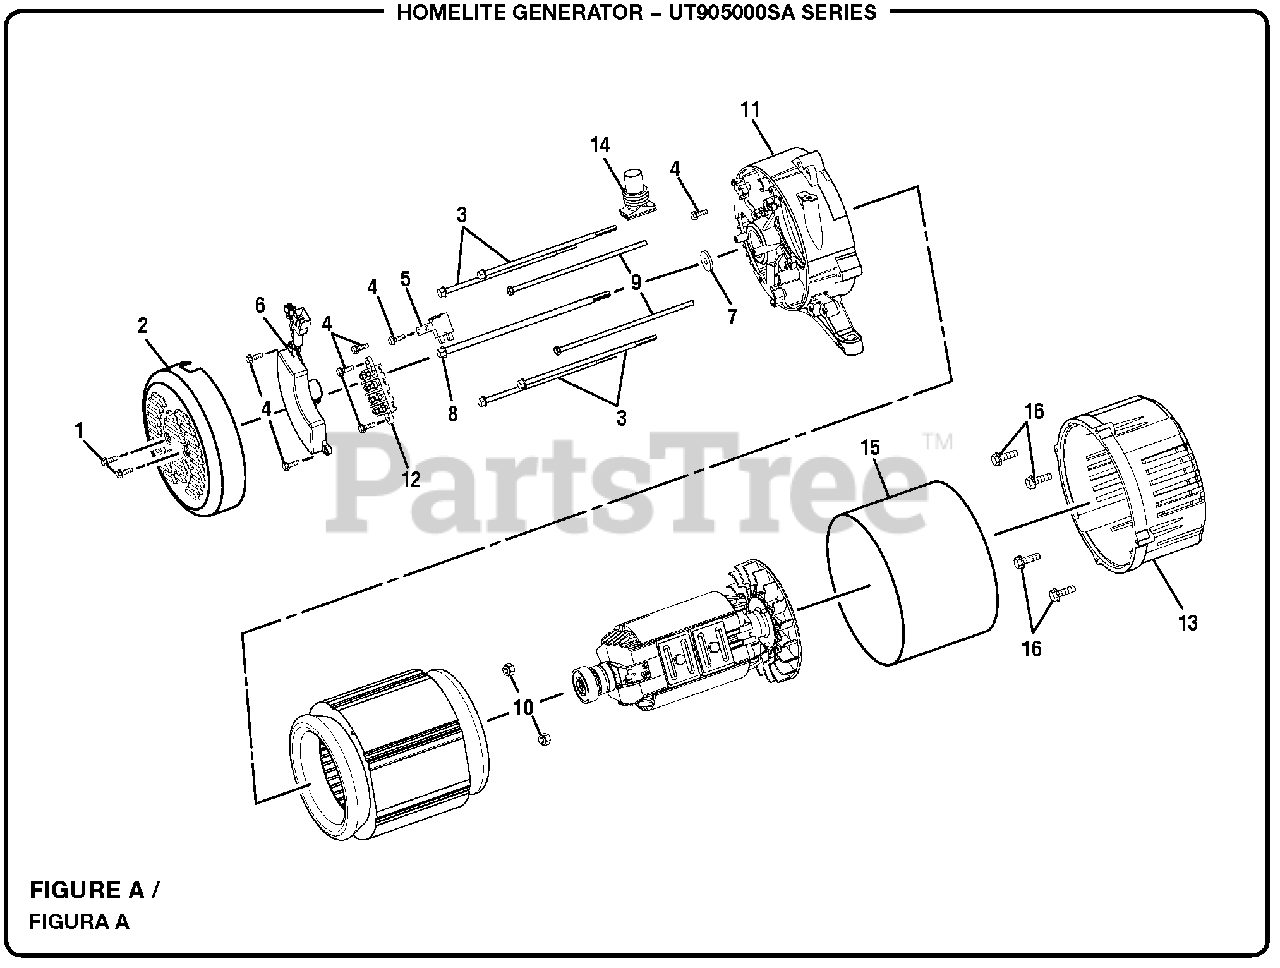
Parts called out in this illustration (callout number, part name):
1	Bolt (M5 x 10 mm, FlangeHex Hd)
2	Brush Cover
3	Bolt (1/4-20 x 6 in, Hex Hd)
4	Bolt (M5 x 16 mm, Flange Hex Hd)
5	Brush Assembly
6	Automatic Voltage Regulator
7	Washer (5/16 in)
8	Bolt (5/16-24 x 230 mm, Hex Hd)
9	Bolt (M5 x 230mm, Hex Hd)
10	Hex Nut (M5)
11	Bearing Support
12	Terminal Block
13	Engine Adapter
14	Rubber Boot
16	Bolt (3/8-16 x 1-1/4 in)
